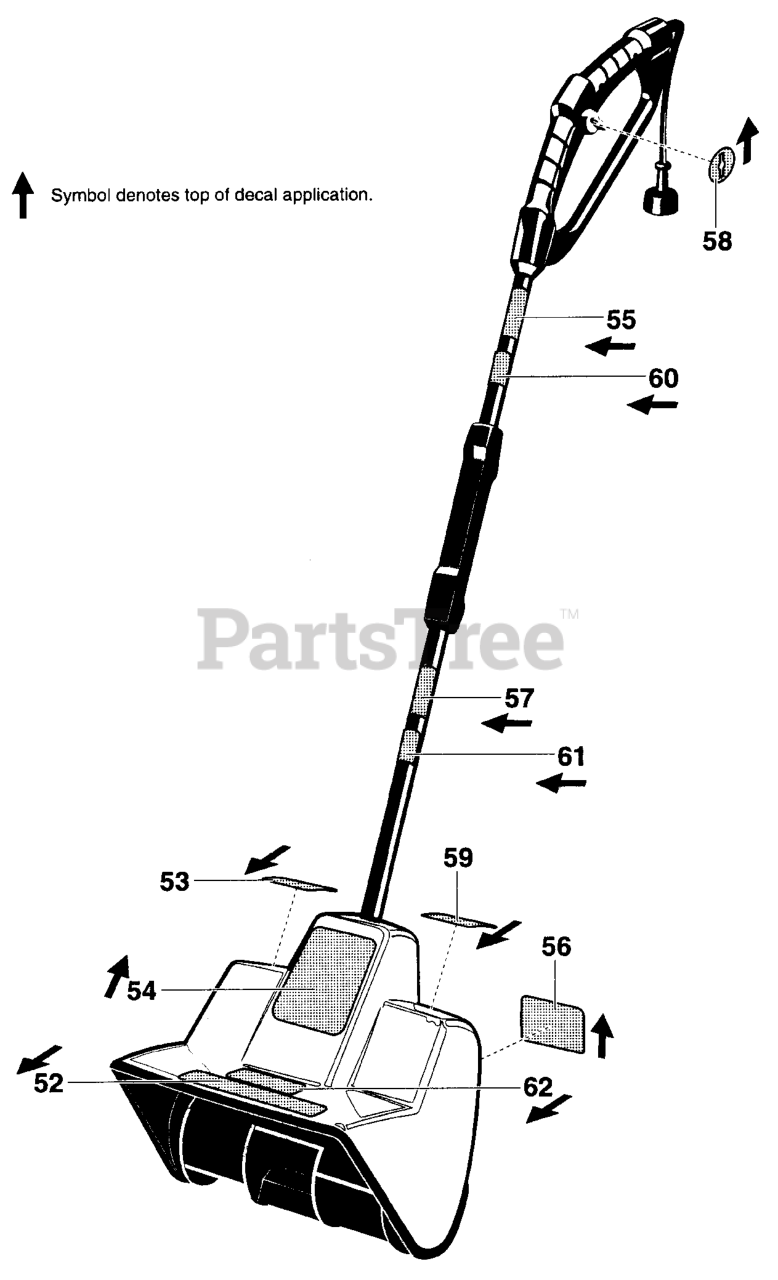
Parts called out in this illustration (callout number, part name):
52	DECAL, DANGER FOOT
53	DECAL, CAUTION E12
54	DECAL, MURRAY
55	DECAL, CORD USAGE 12/14"
56	NOT SERVICEABLE
57	DECAL, PINCHED WIRE
58	DECAL, KEY LOCK
59	DECAL, CAUTION
60	DECAL, MOTOR PROTECTION
61	DECAL, MOTOR PROTECTION
62	DECAL, WARNING
